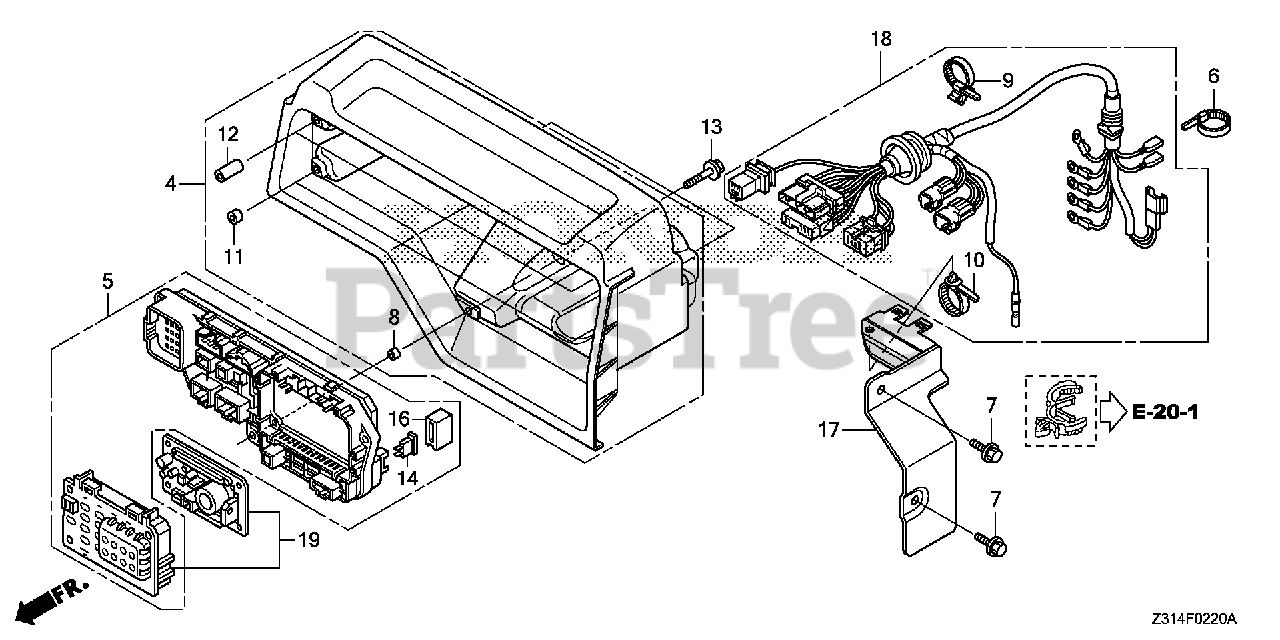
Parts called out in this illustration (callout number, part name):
4	CASE, CONTROL PANEL *NH314* (CONDUCT GRAY)
5	BOX ASSY., JUNCTION
6	TIE, CABLE (C)
7	BOLT, FLANGE (6X12) (CT200)
8	COLLAR, BODY COVER
9	CABLE, STRAP
10	CLIP, HARNESS BAND (145MM) (BLACK)
11	COLLAR, CONTROL CASE
12	COLLAR, CONTROL CASE
13	BOLT, FLANGE (6X20)
14	FUSE, BLADE (10A)
16	COVER, FUSE
17	BASE, HARNESS CLIP
18	WIRE HARNESS ASSY., GENERATOR
19	COVER ASSY., AUTOMATIC VOLTAGE REGULATOR
